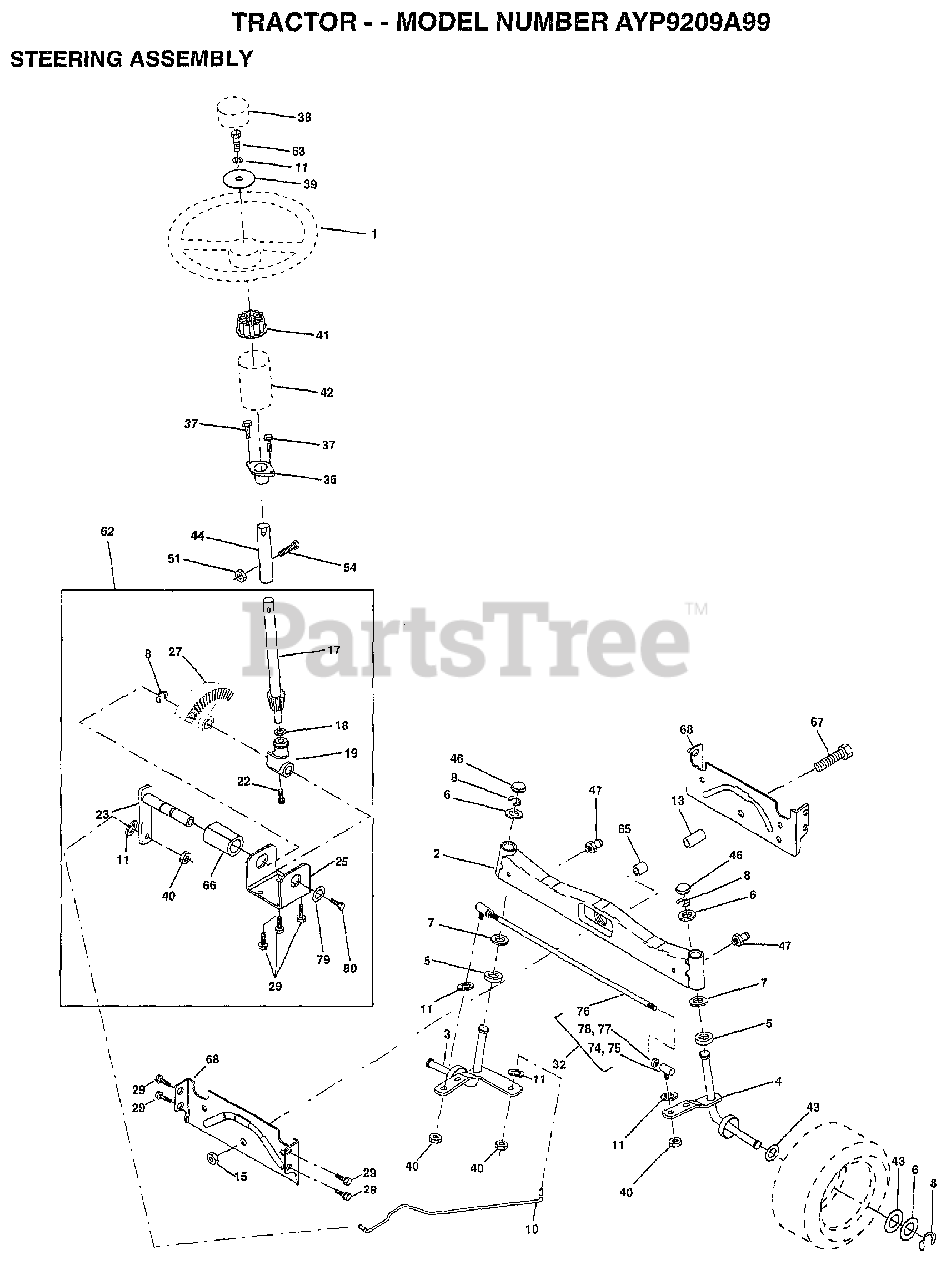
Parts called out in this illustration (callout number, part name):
3	"SPINDLE ASM,LH"
4	"SPINDLE ASM,RH"
5	WASHER .T
6	WASHER
7	WASHER
8	RING
10	LINK.DRAG
11	LOCKWASHER
13	BEARING.FRT.SPACER.AXLE
15	"NUT-LOC,FLANGE LT"
17	SHAFT ASM STEERIN
18	WASHER THRUST
19	SUPPORT.SHAFT.STEER
22	SCREW.HX.WSH.HD
23	SHAFT.ASM.PITMAN
25	BRKT-STEERING
27	GEAR SECTOR
29	SCREW
32	ROD.ASM.TIE.BALL
36	BUSHING.STEERING
37	"SCREW-TT,10-32 FL"
38	"INSERT,STR WHEEL"
39	WASHER T
40	GRIPCO NUT
41	ADAPTER LT
42	BOOT.STEER.PL
43	WASHER
44	EXT SHAFT STEERIN
46	CAP
47	ZERK M
51	NUT
54	BOLT
62	KIT.STEER.ASM
63	BOLT
65	SPACER AXLE
66	"BEARING-ARM,PITMA"
67	BOLT
68	BRACE AXLE
74	JOINT.RH
75	JOINT.LH
77	NUT
78	NUT
79	WASHER
80	BOLT.HX.NYLON3/8-16X3/
